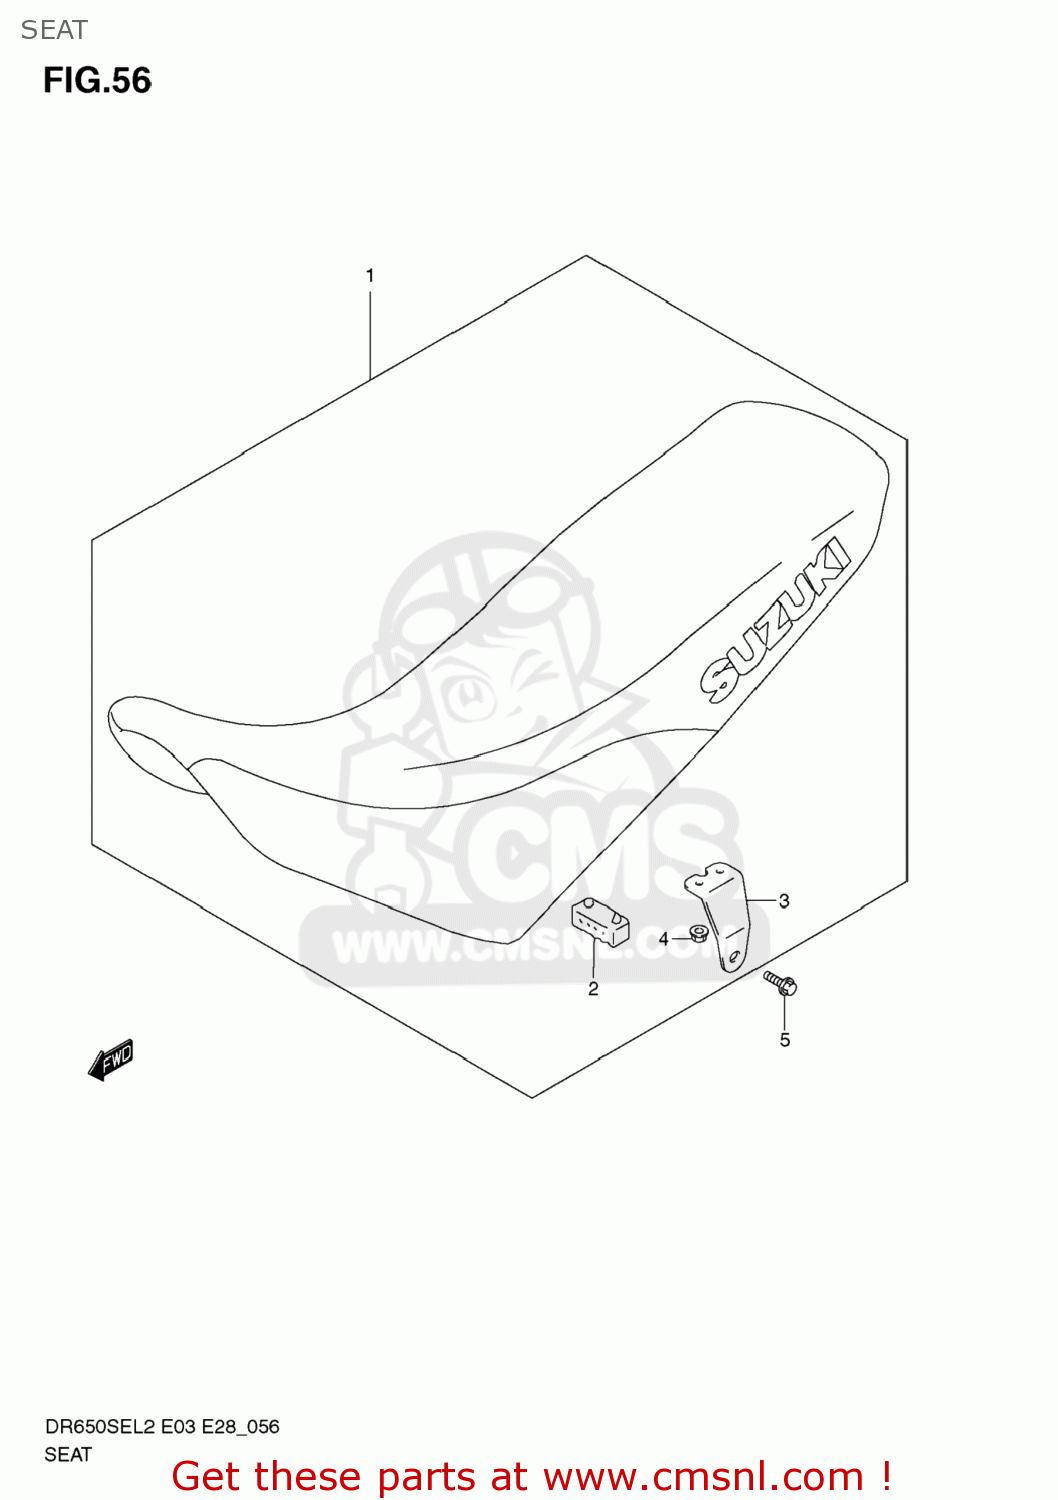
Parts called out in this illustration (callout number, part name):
1	SEAT ASSY
2	CUSHION,SEAT(40X20X15)
3	BRACKET
4	NUT
5	BOLT
